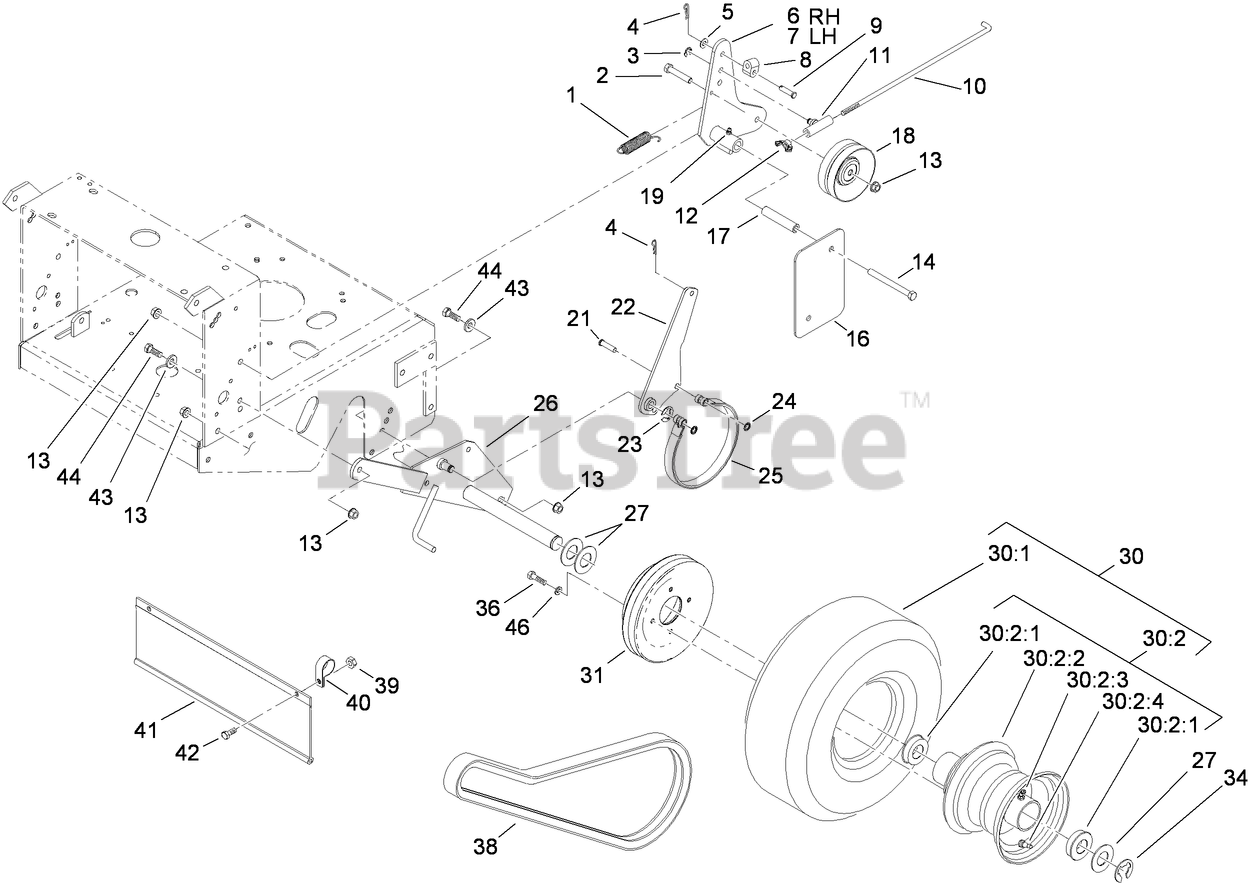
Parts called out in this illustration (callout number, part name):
1	SPRING-EXTENSION
2	SCREW-HH
3	RING-RETAINING
4	PIN-COTTER
5	WASHER-PLAIN
6	ARM-IDLER, RH
7	ARM-IDLER, LH
8	FITTING-ROD
9	PIN-CLEVIS
10	ROD-BRAKE
11	SWIVEL-BRAKE
12	WINGNUT-NYLOCK
13	NUT-HHF, WHIZ
14	SCREW-HH
16	SHIELD-WHEEL, DRIVE
17	SPACER-SHIELD
18	IDLER-DRIVE, WHEEL
19	FITTING-GREASE
21	PIN-CLEVIS
22	ARM-BRAKE
23	RING-RETAINING, EXTERNAL
24	NUT-PUSH
25	BAND-BRAKE
27	WASHER-SPACER
30	Wheel and Tire ASM
30:1	Tire-Turfmaster
30:2	WHEEL AND HUB ASM
30:2:1	BEARING-FLANGED
30:2:2	Rim ASM
30:2:3	Fitting-Grease
30:2:4	Stem-Valve
31	DRUM AND SHEAVE ASM
34	RING-SNAP
36	SCREW-HH
38	V-BELT
39	NUT-LOCK, NI
40	CLAMP-R
41	SHIELD-TRAILING
42	SCREW-HH
43	WASHER-BELLEVILLE
44	SCREW-HH
46	WASHER-LOCK
